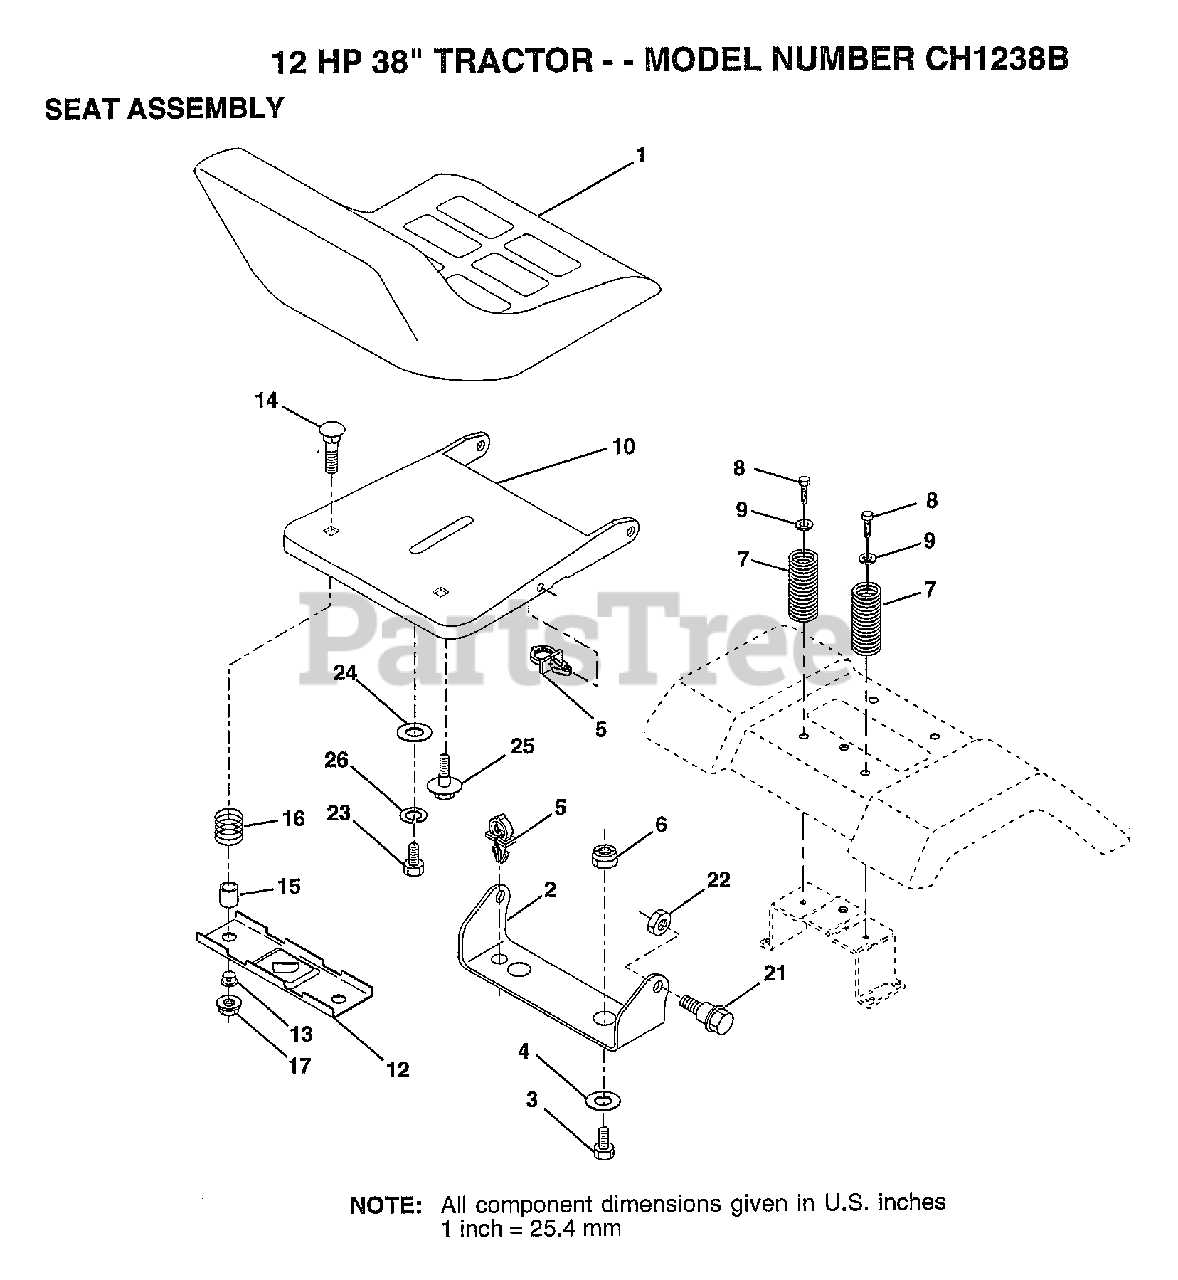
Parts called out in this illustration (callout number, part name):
2	BRACKET PVT SEAT
4	WASHER PM
5	CLIP PUSH - IN
6	NUT
7	SPRING COMPRESSIO
8	SCREW GTV
9	WASHER
12	BRKT SWITCH
13	BUSHING
15	SPLIT SPACER
16	SPRING
21	BOLT.SHLD.5/16-18
23	BOLT
24	WASHER
25	"BOLT,SHOULDER"
26	LOCKWASHER
